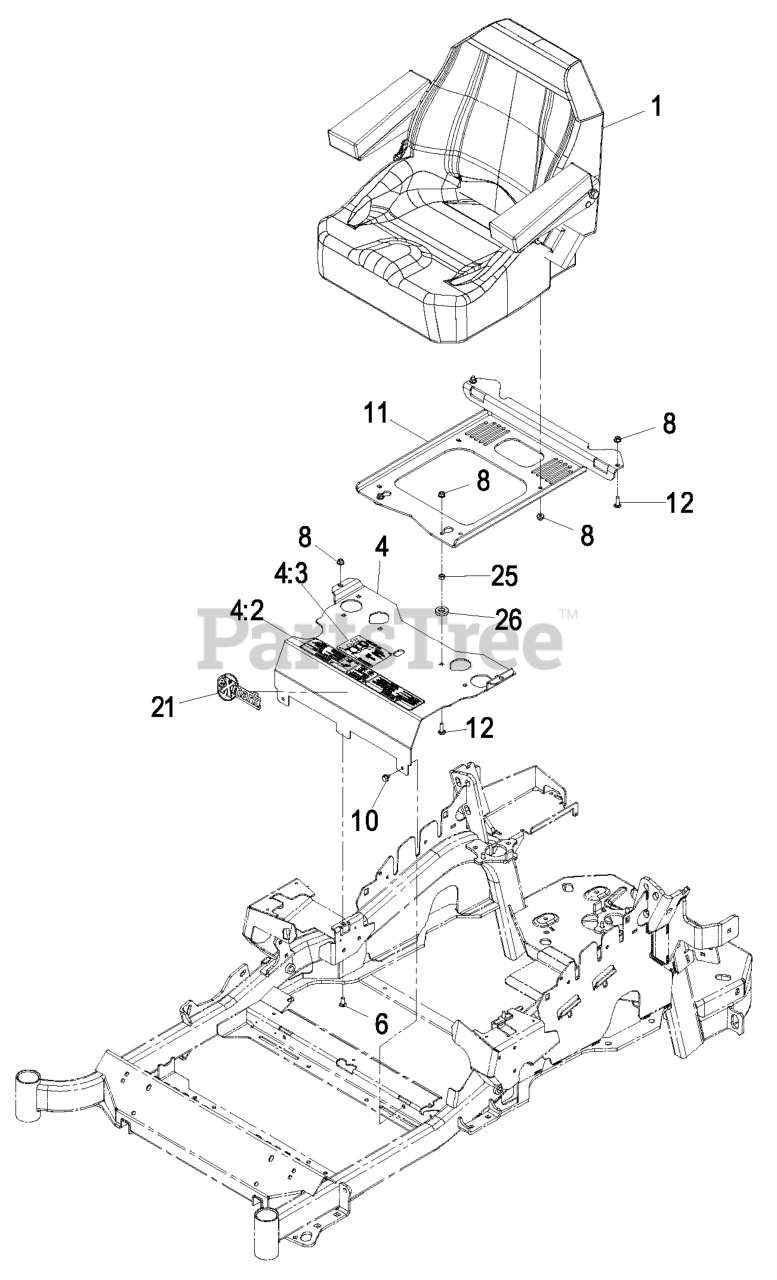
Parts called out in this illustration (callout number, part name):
4	MOUNT-SEAT
4:2	DECAL-CONSOLE
4:3	DECAL-SERVICE AID
6	SCREW-CARR
8	NUT-HF, NI
11	PLATE-SUPPORT, SEAT
12	SCREW-CARR
25	NUT-HEX
